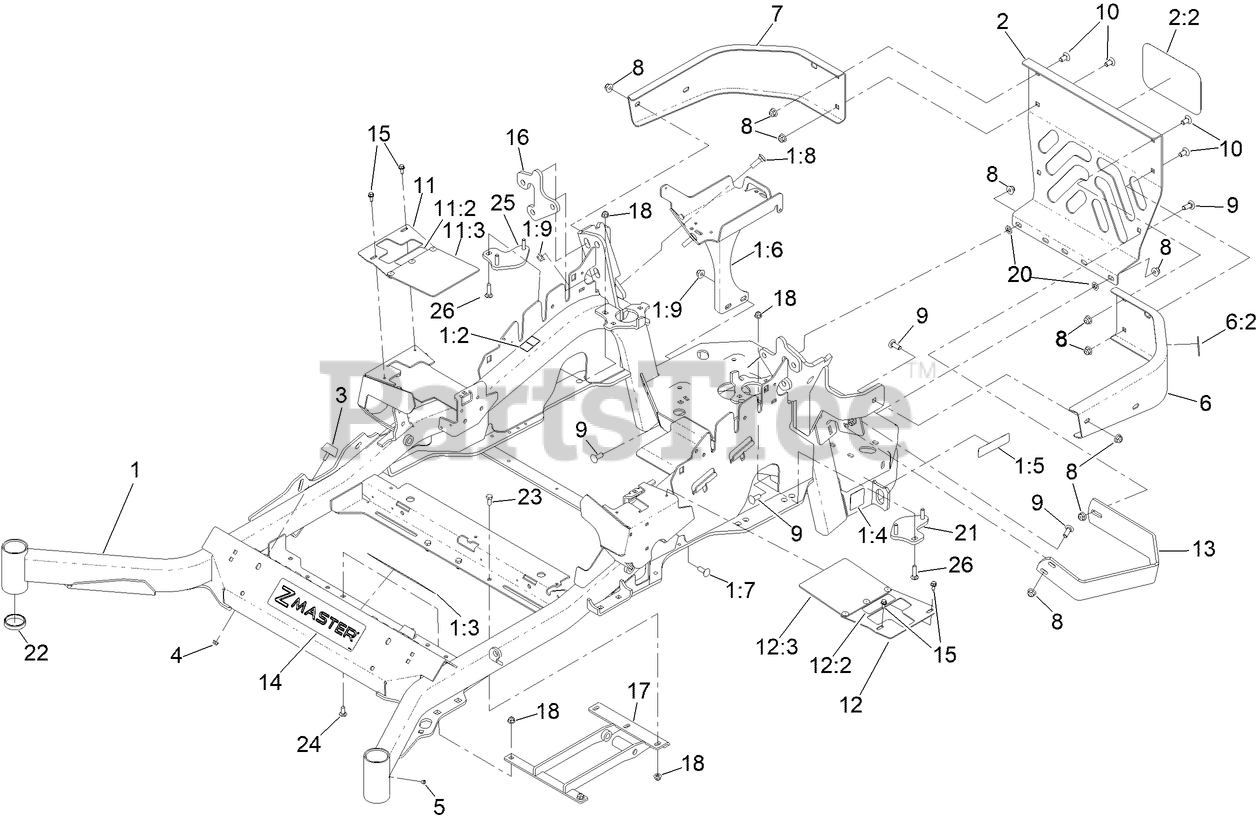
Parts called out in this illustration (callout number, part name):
1	MAINFRAME SERVICE ASM - 72
1:2	DECAL-WARNING
1:3	DECAL-DANGER
1:4	DECAL-HAZARD, PINCHED FINGER
1:5	DECAL-ARRESTOR, SPARK
1:6	BATTERY MOUNT ASM
1:7	SCREW-CARR
1:8	BOLT-CARR
1:9	NUT-HF, NI
2	REAR GUARD ASM
2:2	DECAL
3	BUMPER
4	NUT-HF
6	LH BUMPER ASM
6:2	DECAL-WARNING
7	BUMPER-RH
8	NUT-HF, NI
9	SCREW-CARR
10	SCREW-CARR
11	RH MOTION CONTROL COVER ASM
11:2	DECAL-CONTROL, MOTION
11:3	FLAP-RUBBER
12	LH MOTION CONTROL COVER ASM
12:2	DECAL-CONTROL, MOTION
12:3	FLAP-RUBBER
13	GUARD-MUFFLER
14	DECAL-CONSOLE
15	SCREW-HWH
16	PLATE-MOUNT, SHOCK
17	MOUNT-LOWER
18	NUT-HF, NI
20	NUT-PUSH
21	LH PLATE ASM (W/STUDS)
22	CUP-BEARING
23	SCREW-HH
24	SCREW-CARR
25	RH PLATE ASM (W/STUDS)
26	SCREW-CARR
